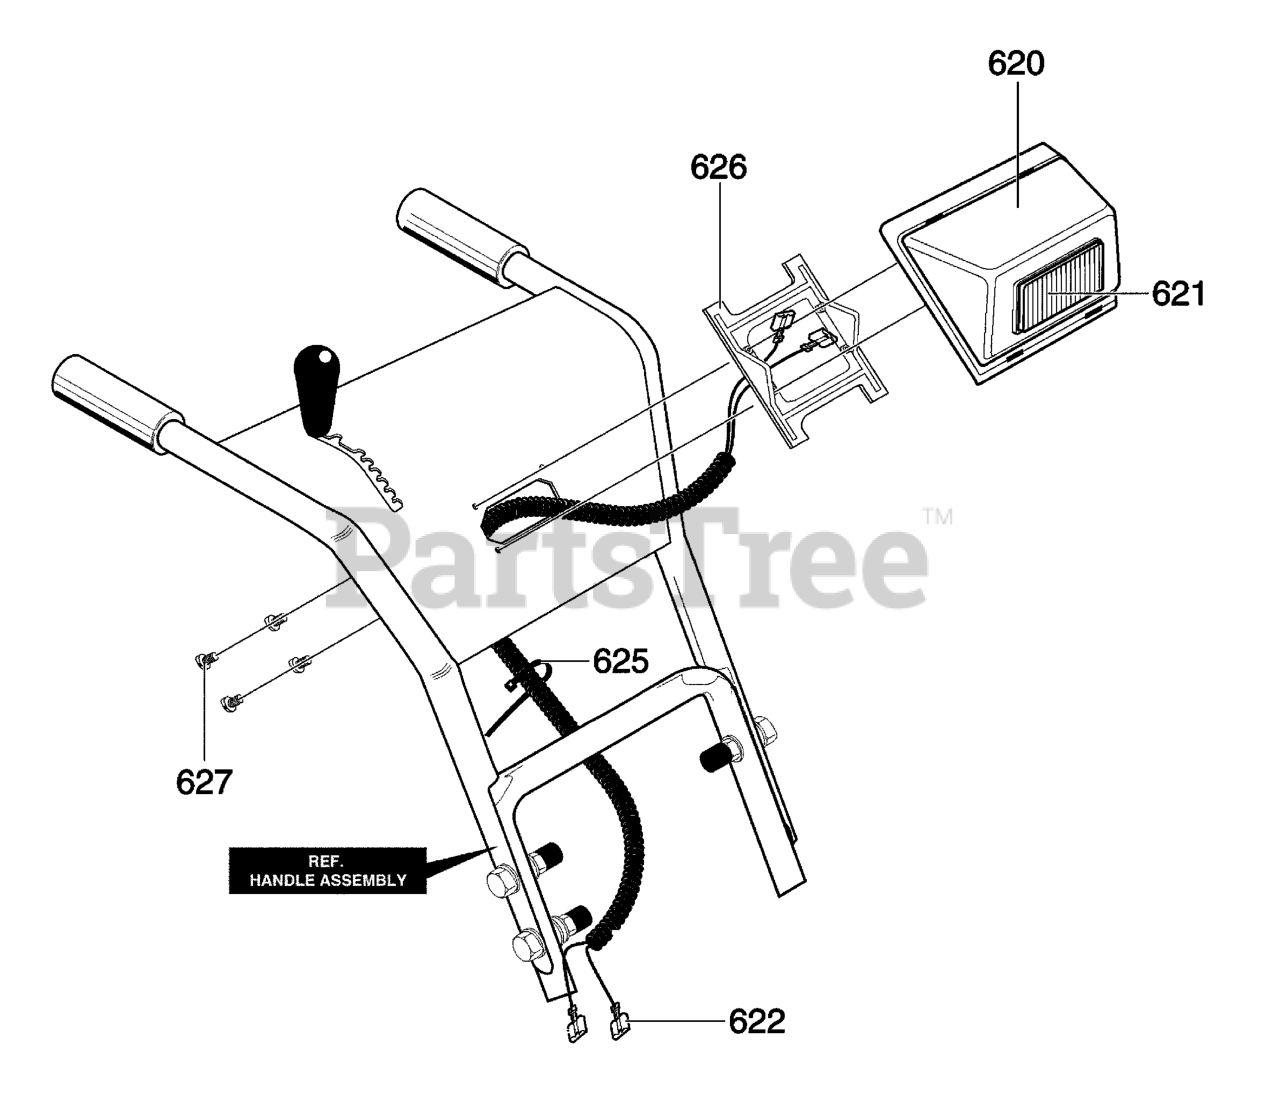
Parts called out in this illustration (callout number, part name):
620	HEADLAMP HOUSING
621	HEADLIGHT ASSY
622	WIRE, HARNESS
625	CABLE TIE
626	BRACKET, HEADLAMP
